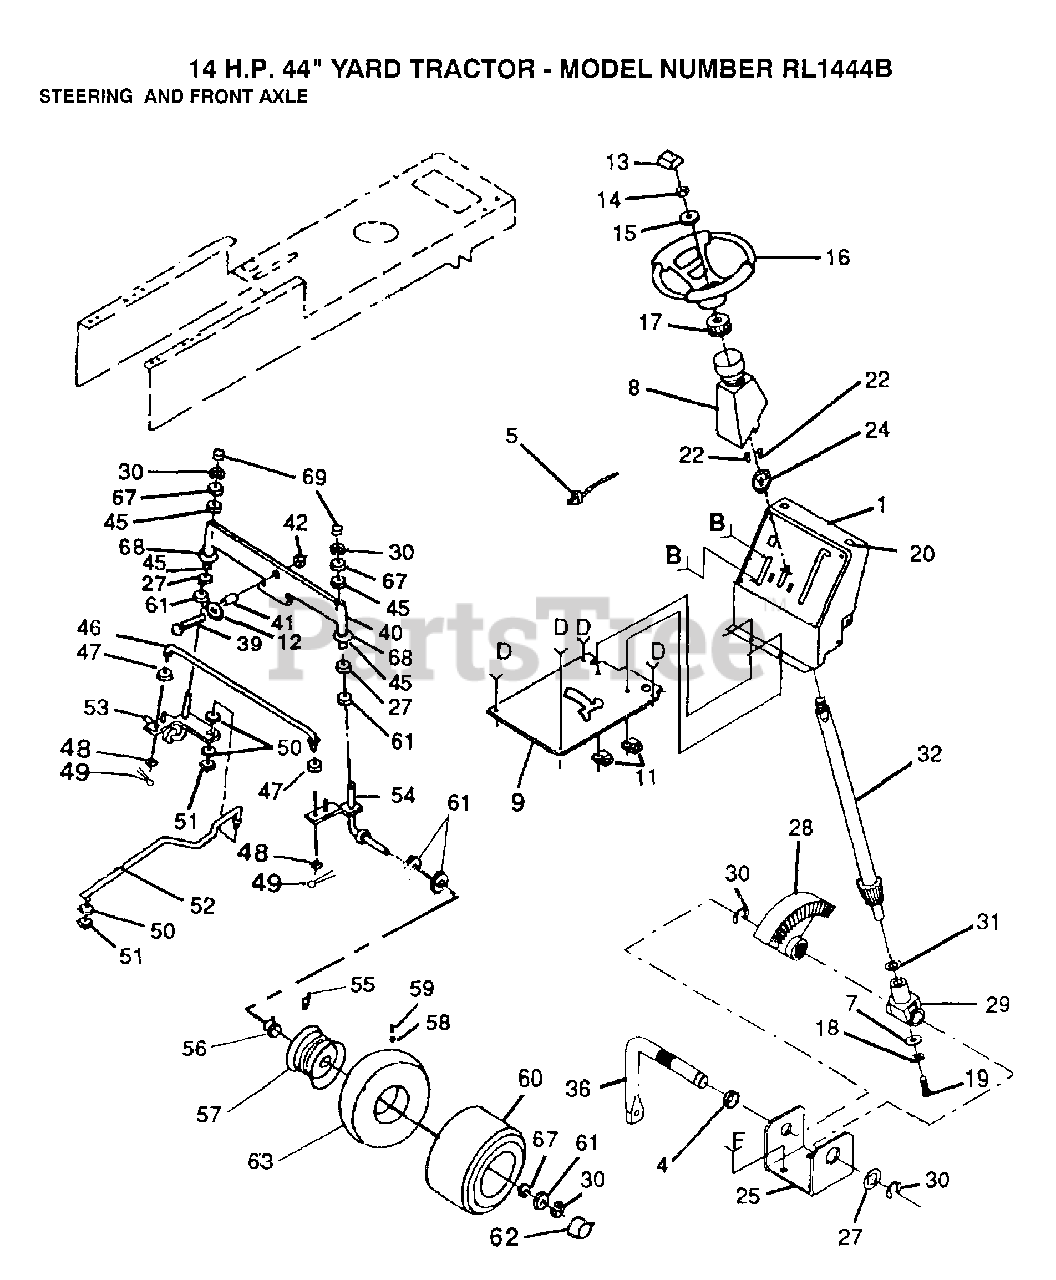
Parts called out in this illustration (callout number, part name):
4	NYLINER T
8	"TUBE, STR SHAFT"
11	CLIP T
13	INSERT-WHEEL LT
15	WASHER
17	ADAPTER LT
18	LOCKWASHER
19	"SCREW,SPECIAL"
24	"BUSHING,STEERING"
25	"BRKT,STEERING"
27	WASHER .T
29	SUPPORT.SHAFT
30	RING
31	THRUST WASHER
32	SHAFT WELD STR T
39	BOLT LT
41	BEARING
45	COL. SRTG. BEAR.
48	WASHER
49	COTTER PIN
50	LOCKWASHER
53	SPINDLE-LH LT
55	FITTING LT
56	"FLANGE, BEARING"
58	VALVE CAP
59	VALVE STEM LT
61	WASHER
62	HUB CAP
63	TUBE.5.3/4.5/6
67	WASHER
68	WASHER
69	CAP
